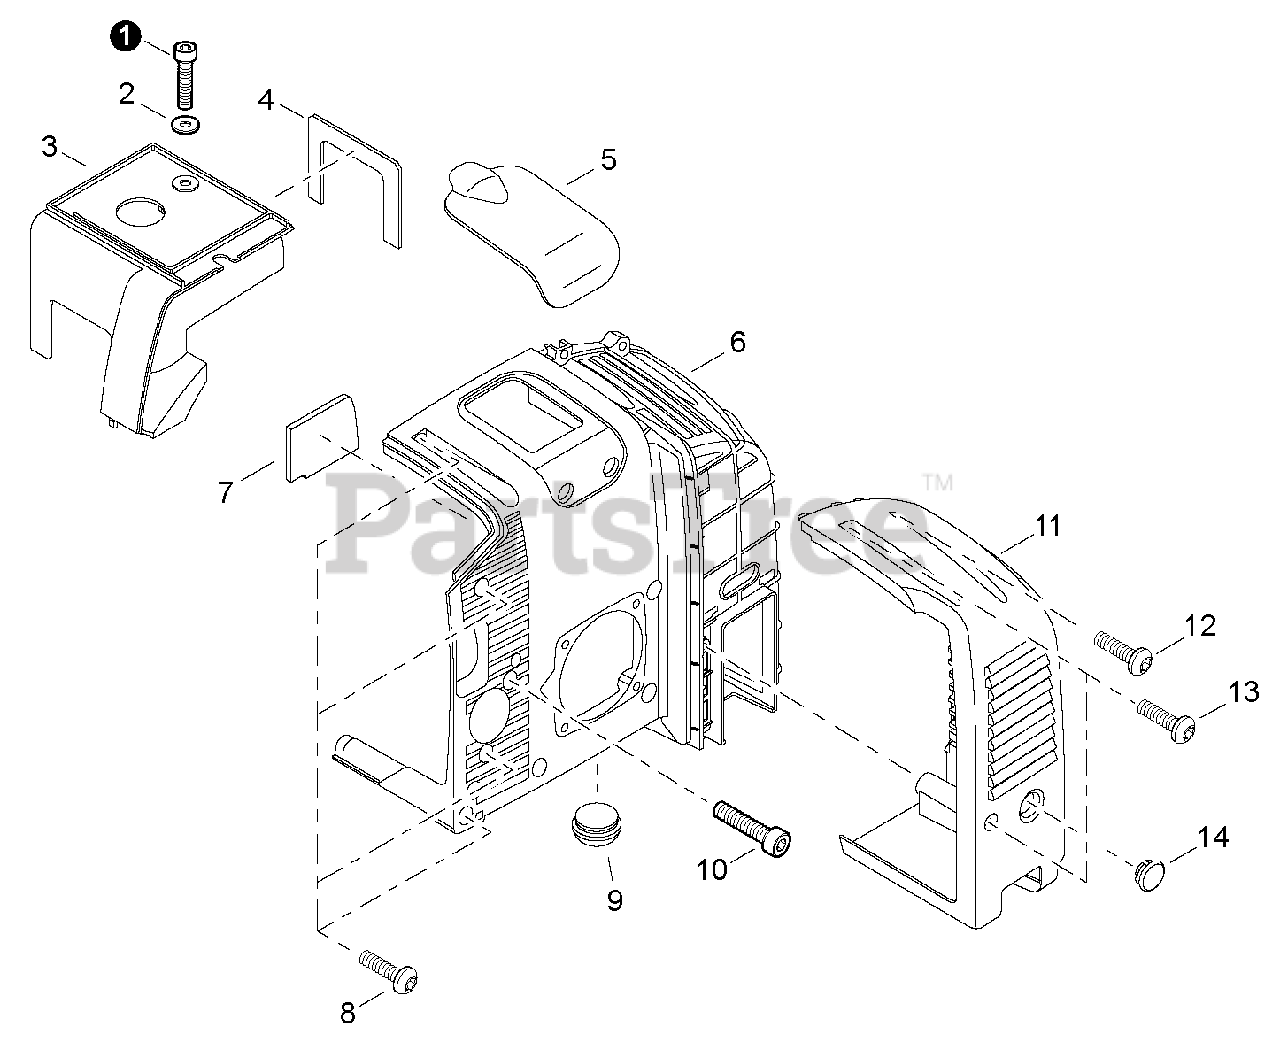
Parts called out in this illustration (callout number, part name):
1	BOLT, TORX 5×20
2	WASHER 5.2×14×T3
3	COVER, CYLINDER
4	PLATE, INSULATOR
5	COVER, SPARK PLUG
6	COVER, ENGINE
7	PLATE, INSULATOR
8	BOLT, TORX 5×20
9	CUSHION
10	BOLT, TORX 5×16
11	COVER, MUFFLER
12	BOLT, TORX 5×25
13	BOLT, TORX 5×16
